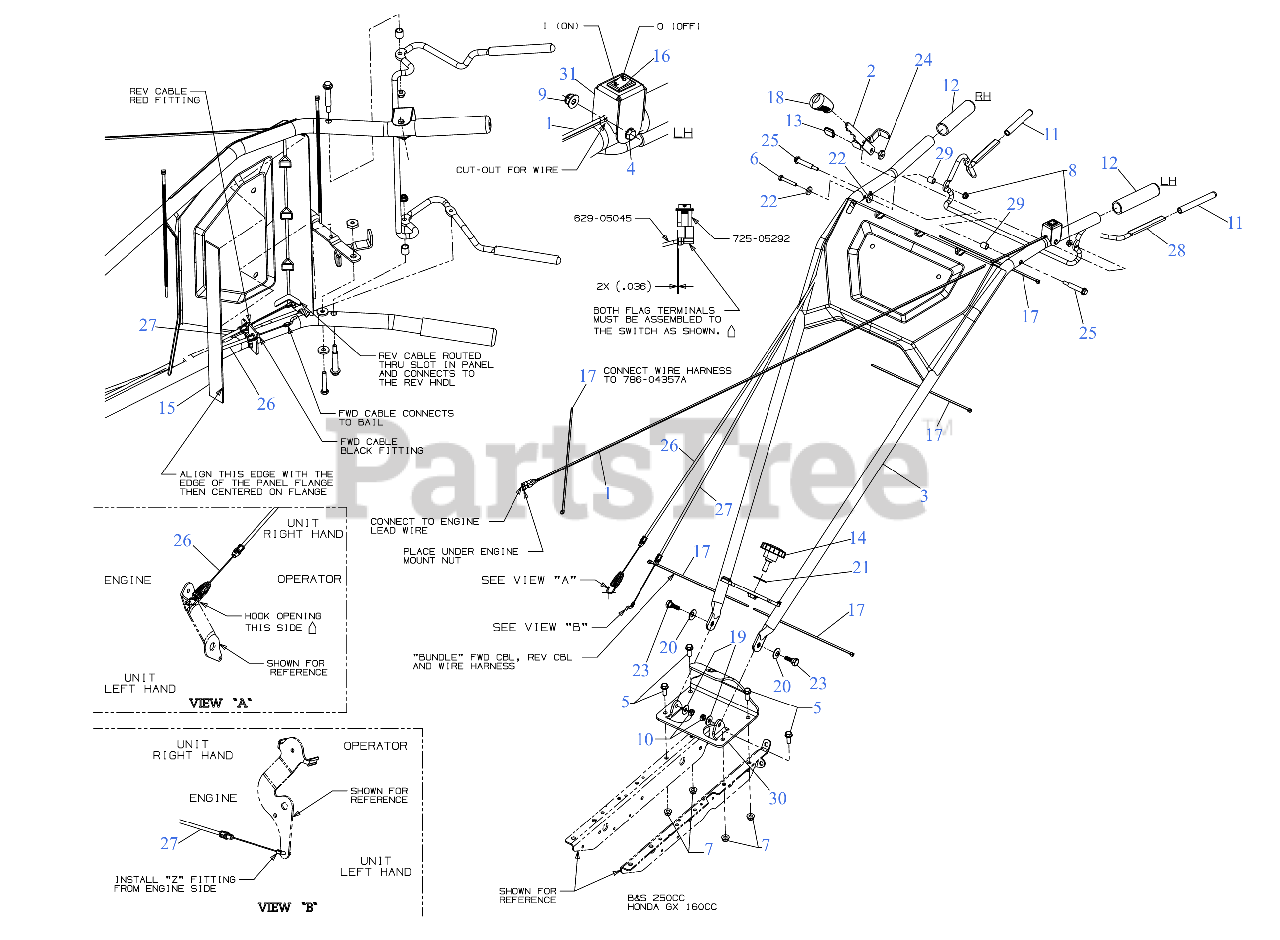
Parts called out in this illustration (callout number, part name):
1	HARNESS ASSEMBLY
4	SCREW HEX HD WASHER (#10-32 x 1.50)
5	SCREW 5/16-18 x .875 GR5
6	BOLT 1/4-20X1.62 GR5
7	FLANGE LOCK NUT 5/16-18
8	FLANGE LOCK NUT
10	HEX NUT LOCK CENTER
11	CLUTCH GRIP
13	REVERSE HANDLE GRIP
14	STAR KNOB 3/8-16
15	TAPE FOAM 1.25 x 13.53 x .10
16	POSITIVE SWITCH- ON/OFF
18	BRAKE HANDLE GRIP
19	FLAT WASHER
20	BELL WASHER
21	BELL WASHER
22	FLAT WASHER
23	SHOULDER SCREW .437 DIA x .265
24	SHOULDER SPACER
25	SHOULDER SCREW .375 x 1.62 x 1/4-20
26	FORWARD CABLE
27	REVERSE CABLE
31	SWITCH MOUNT BRACKET
